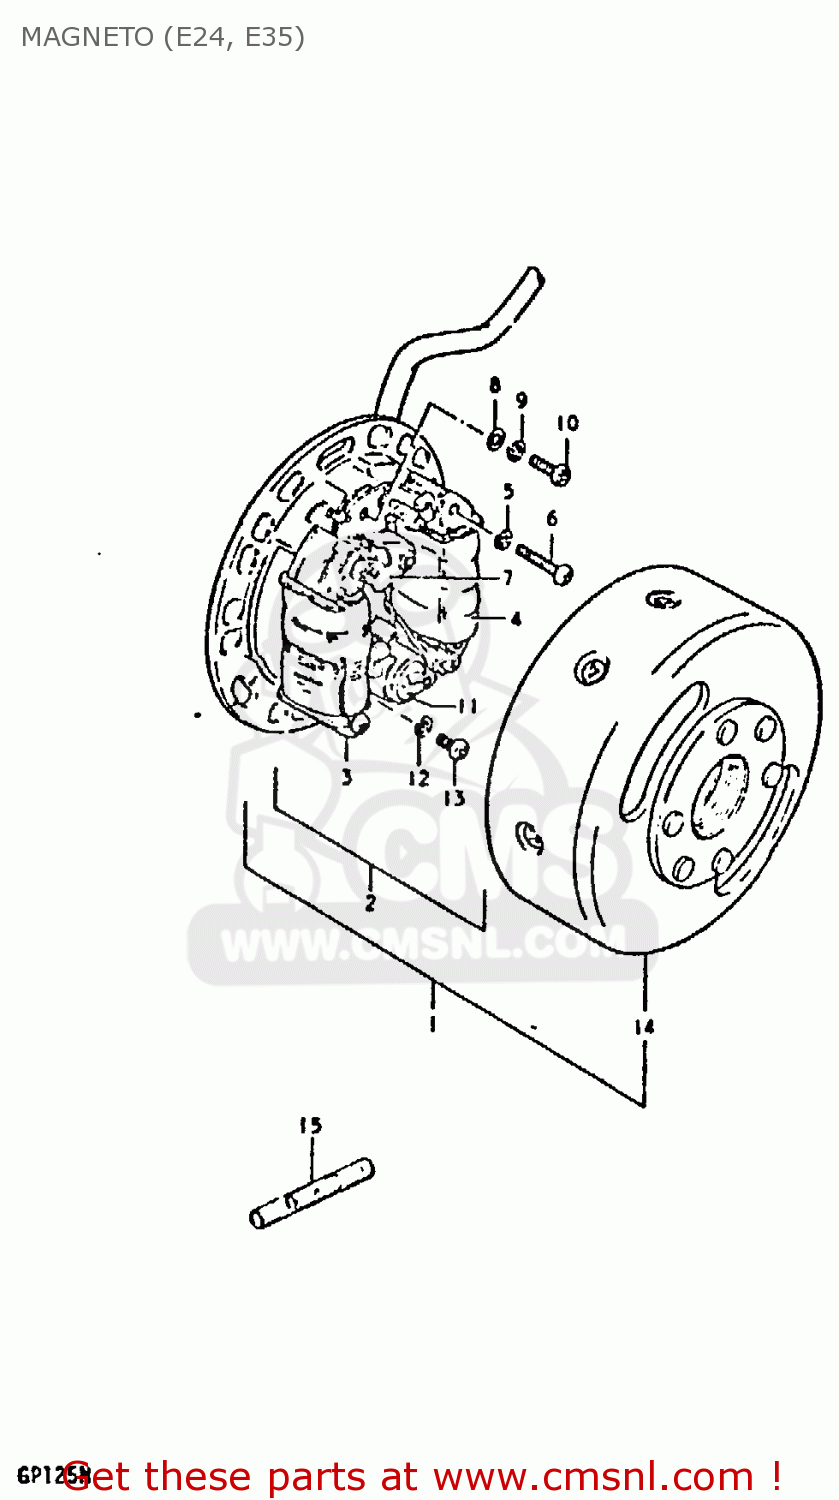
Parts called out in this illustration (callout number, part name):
1	MAGNETO ASSY
2	STARTER ASSY
3	COIL,LIGHTING
4	COIL,PRIMARY
5	LOCK WASHER
6	SCREW (4X30)
7	POINT ASSY,CONTACT
8	WASHER
9	LOCK WASHER
10	SCREW(4X10)
11	CONDENSER
12	LOCK WASHER
13	SCREW
14	ROTOR, FRYWHEEL
15	CONNECTOR
